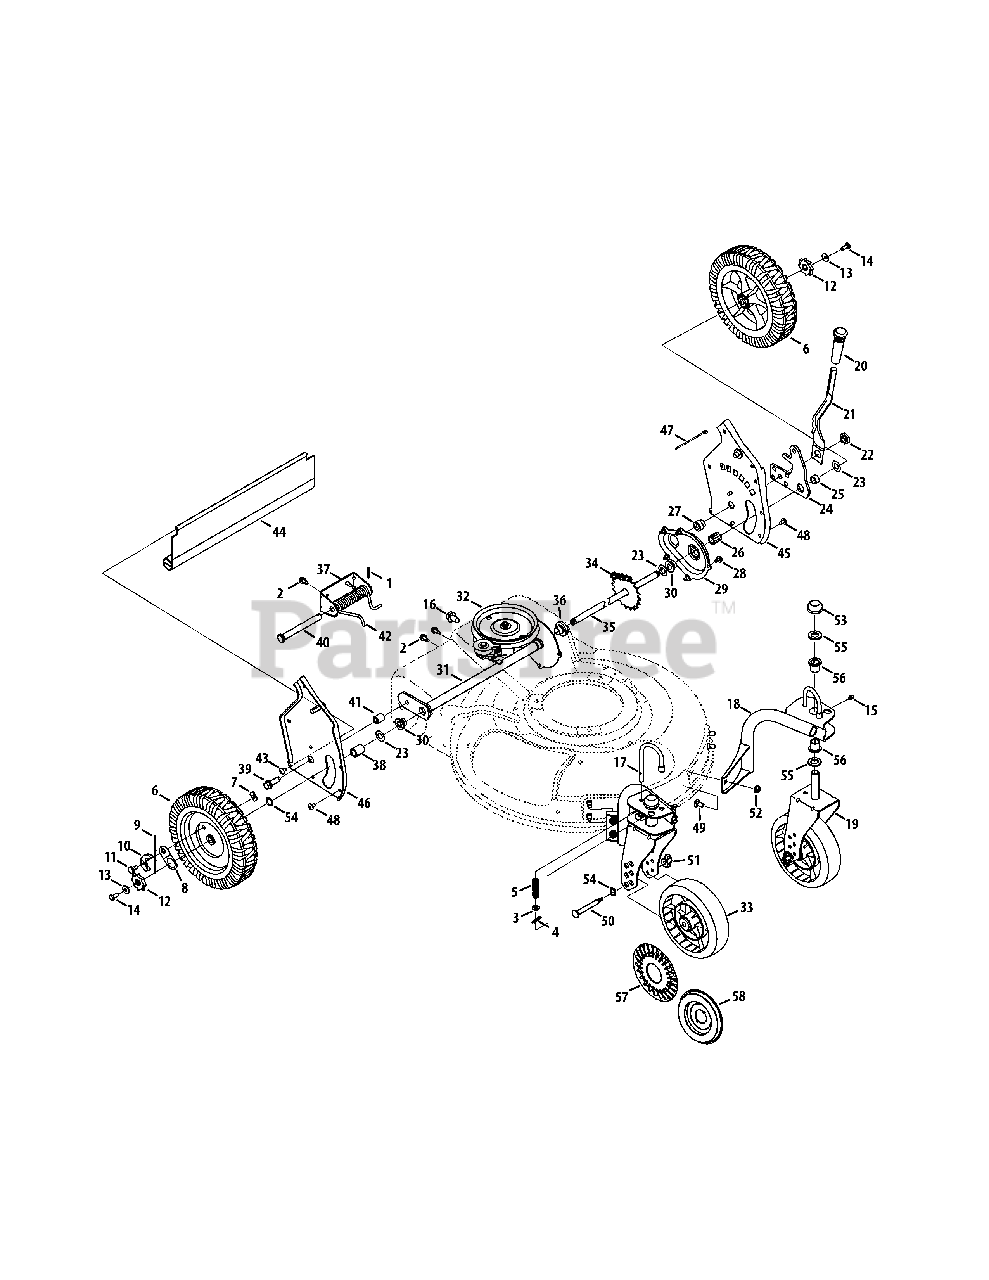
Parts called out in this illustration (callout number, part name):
1	Cotter Pin
2	Screw 1/4-14 x .825
3	Flat Washer.330 ID x.630 OD
4	Cotter Pin
5	Compression Spring
6	Wheel, 9 x 2.125
7	Top Lock Tab Weld Nut 1/4-20
8	Ratchet Pawl Plate
9	Plastic Spring Ratchet
10	Pawl RH
10	Pawl LH
11	Shlder Screw.340 ID x.285 OD
12	Wheel Ratchet
13	Bell Washer.265 ID x.75 OD
14	Hex Cap Screw 1/4-20 x.620
15	Grease Fitting
16	Screw, 5/16-18 x .625
17	Wheel Pin Lock
18	Caster Assembly RH
18	Caster Assembly LH
19	Caster Bracket Assembly RH
19	Caster Bracket Assembly LH
21	Spring Lever
22	Shoulder Nut.825 x .165 Lg.
23	Flat Washer .508 ID x 1.0 OD
24	Pivot Arm Assembly
25	Spacer .510 ID x .70 OD
26	Slv Bearing .504 ID x .830 OD
27	Shlder Spacer, .385ID x .715Lg
28	Tap Screw 1/4-20 x .375
29	Chain Cover Assembly
30	Flge Bearing .506 ID x .590 Lg
31	Transmission Axle Assembly
32	Transmission Ass’y Complete
33	Wheel 7 x 2
34	Chain
35	Rear Axle Assembly
36	Flge Bearing .506 ID x .715 Lg
37	Height Adjustment Spring Brkt.
38	Spacer .550 ID x .750 OD
39	Screw 3/8-16 x .25
40	Clevis Pin .50 Dia x 4.82 Lg.
41	Spacer .385 ID x .624 OD
42	Torsion Spring
43	AB Screw, #10-16 x .500
44	Trail Shield
45	Handle Bracket Assembly - LH
46	Handle Bracket Assembly - RH
47	Cable Tie
48	Screw 1/4-14 x.500
49	Carriage Bolt 5/16-18 x.62
50	Caster Axle
51	Wing Nut
52	Flange Lock Nut 5/16-18
53	Push Cap
54	Wave Washer.510 ID x.750 OD
55	Flat Washer.640 ID x 1.12 OD
56	Flange Bearing
57	Hubcap - Spoke w/ Hole
58	Hubcap - Radial Spoke
